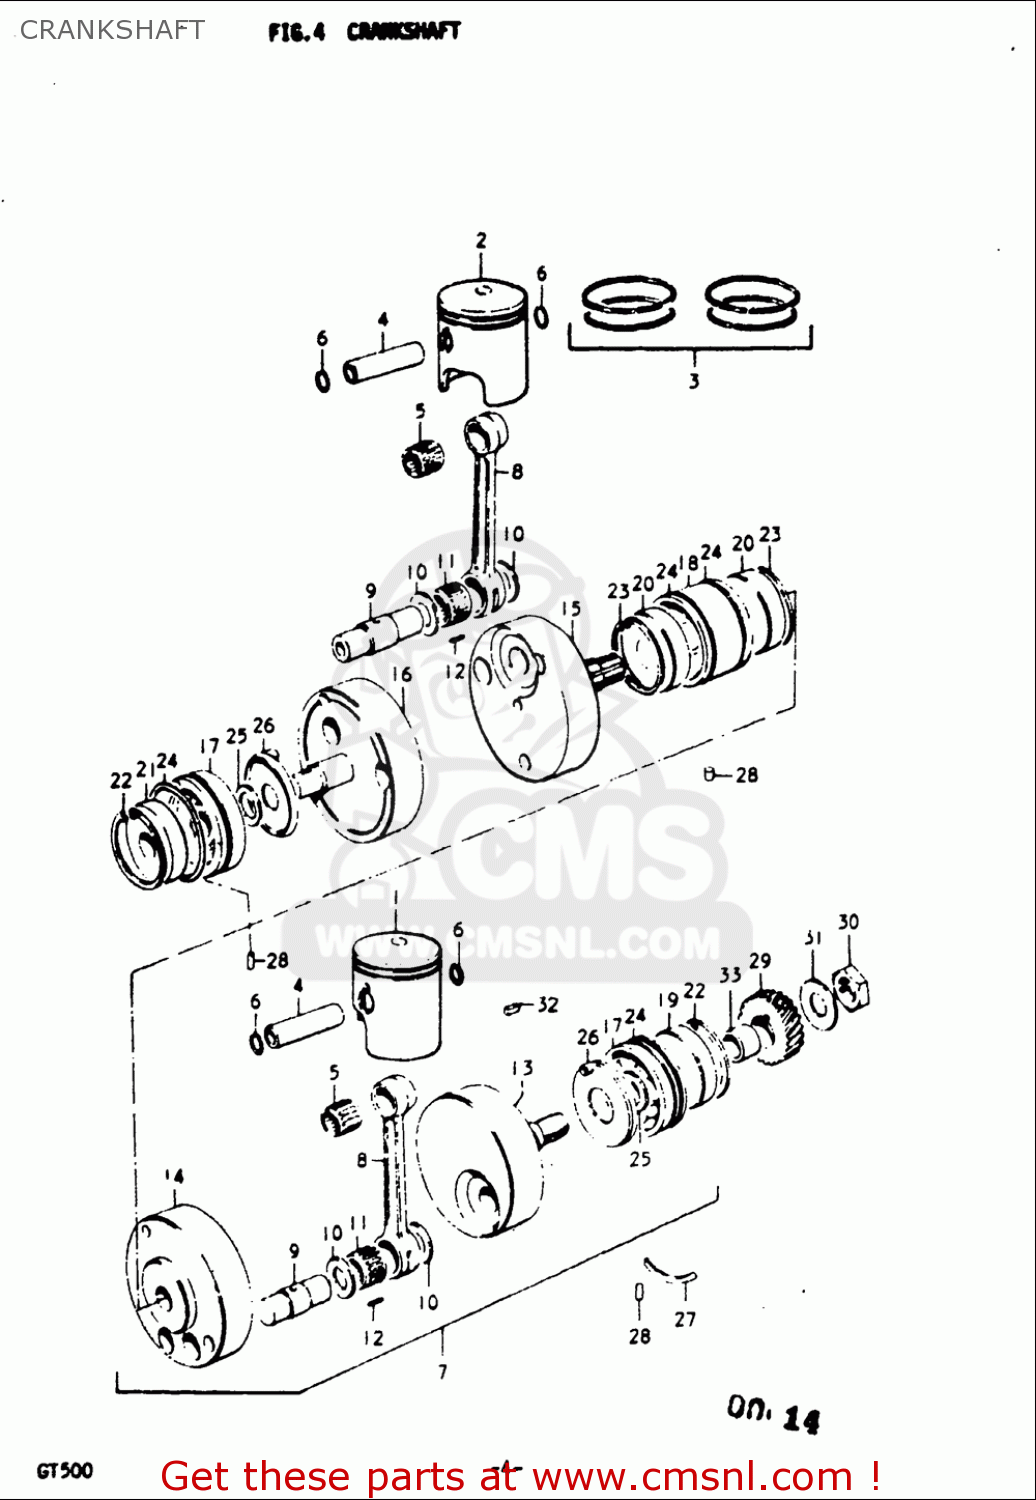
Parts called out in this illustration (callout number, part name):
1	PISTON SET(OS:0.5)
2	PISTON,L
3	RING SET,PISTON
4	PIN,PISTON (18MM)
5	BEARING(18X23X24)
6	CIRCLIP,PISTON PIN
9	PIN,CRANK
12	ROLLER
20	SEAL,OIL(30X65X8)
21	SEAL,OIL(25X62X8)
